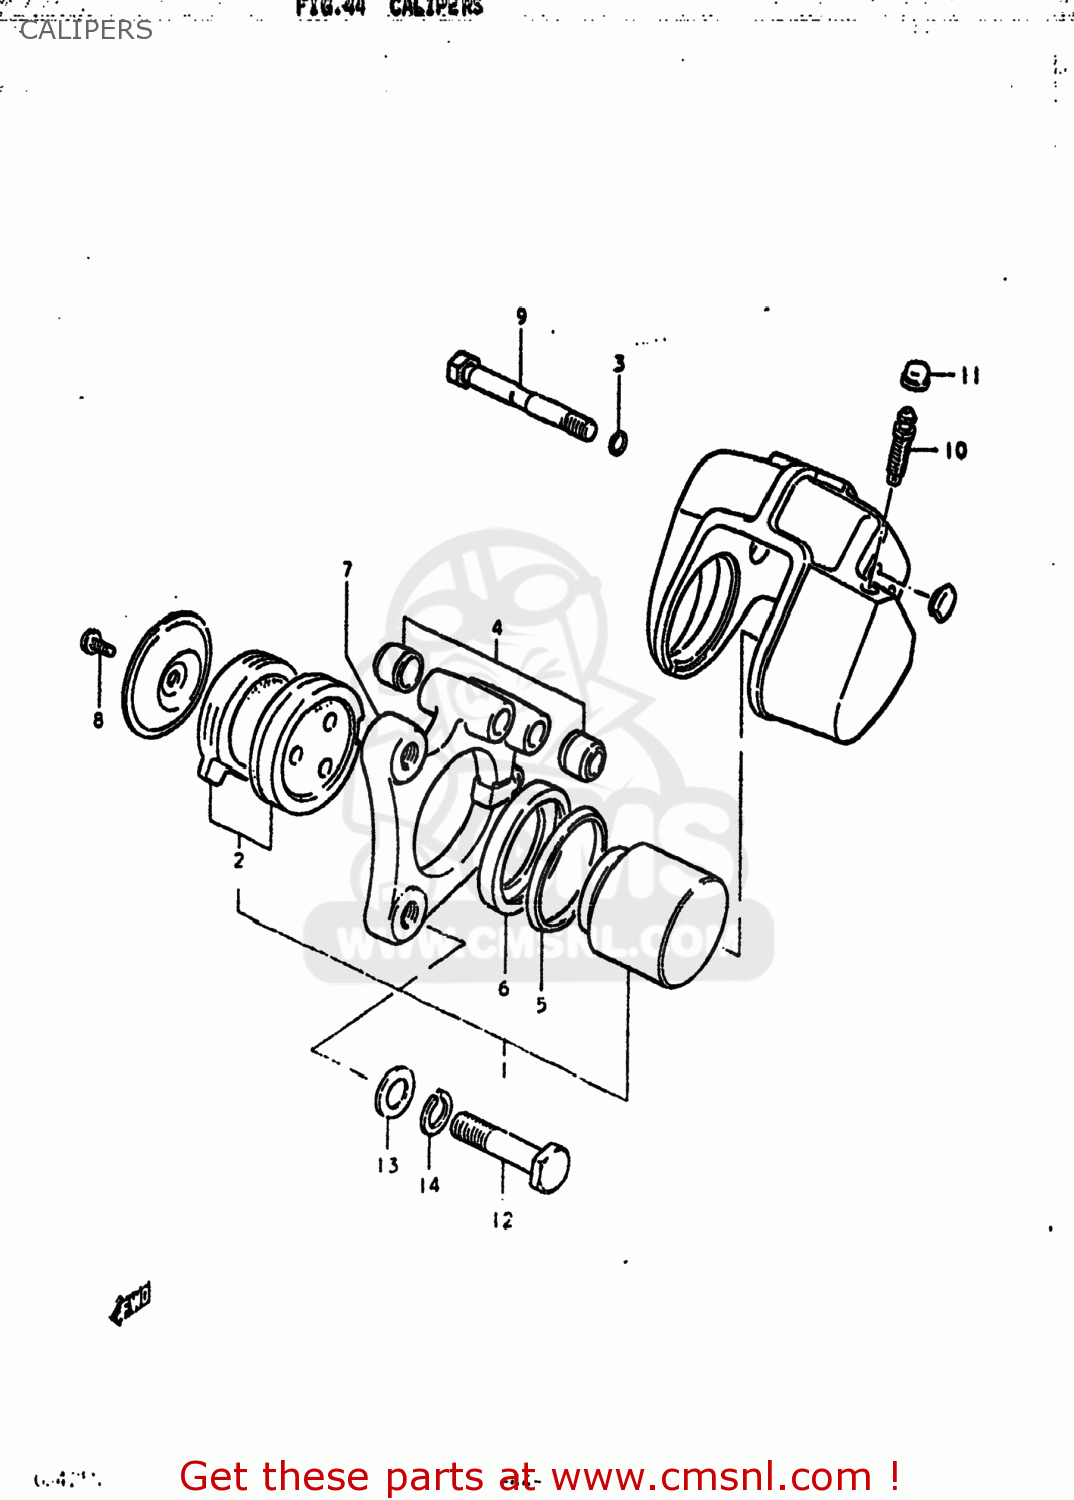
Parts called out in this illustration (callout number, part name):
1	CARRIER,CALIPER,RIGHT
2	CARRIER,CALIPER,LEFT
3	O RING
4	COVER,AXLE DUST
5	SEAL,FR CALIPE
6	BOOT,PISTON
7	HOLDER, CARIPERS LH
8	SCREW 6X12
9	AXLE,CALIPER
10	BLEEDER
11	CAP,BREATHER
12	BOLT
13	WASHER
14	LOCK WASHER
